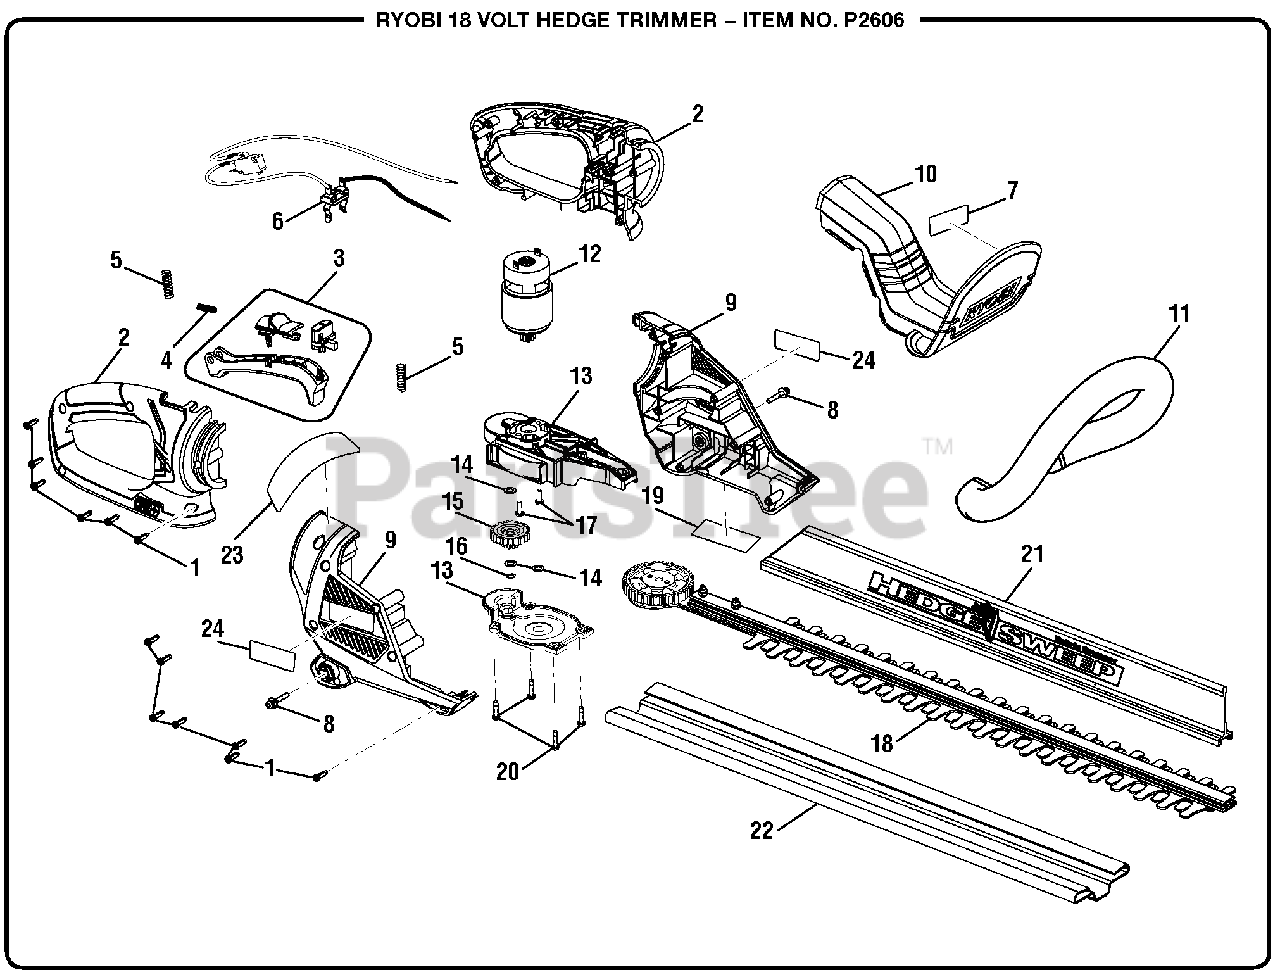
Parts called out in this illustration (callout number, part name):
1	Screw (M4 x 14 mm, T15 Torx Pan Hd.)
2	Handle Assembly
3	Trigger Assembly
4	Compression Spring
5	Compression Spring
6	Wiring Harness
7	Warning Icon Label
8	Screw w/Washers (M4 x 26 mm, T15 Torx Pan Hd.)
9	Housing Assembly
10	Top Cover Assembly
11	Front Handle
12	Motor and Pinion Assembly
13	Gear Box w/Cover Assembly
14	Washer (M6, OD11 x ID6.2 x 0.3t)
15	Center Gear
16	Retaining Ring
17	Screw w/Tooth Washer (M4 x 12 mm, Pan Hd.)
18	Blade Assembly
19	Data Label
20	Screw (M4 x 16 mm, Pan Hd.)
21	Hedge Sweep
22	Blade Shield
23	Rotating Handle Label
24	Logo Label
